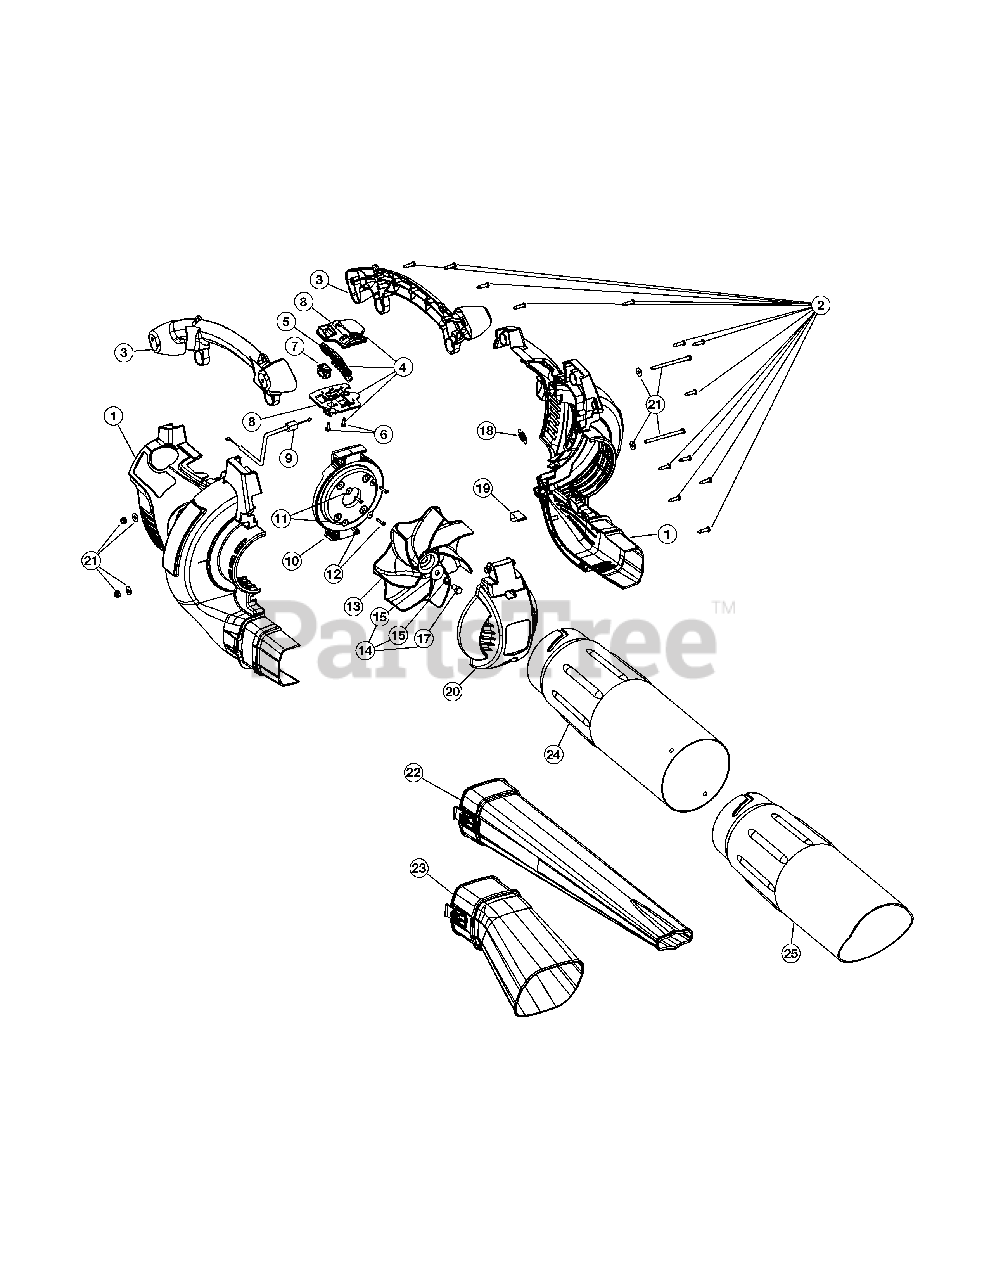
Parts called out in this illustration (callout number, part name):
1	Engine Cover Assm
3	Handle Assm
4	Throttle control Assm
5	Throttle Control Lever
7	Rocker Switch Assm
8	Lower Throttle Control Plate
9	Throttle Cable
10	Engine Mount Plate
13	Impeller Blade
14	Impeller Hardware
15	Washer
16	Lock Washer
18	Vacuum Door Spring
19	Vacuum Door Lock
20	Vacuum Door
21	Mounting Plate Hardware
22	Blower Tube
23	Vacuum Bag Adaptor
24	Upper Vacuum Tube
25	Lower Vacuum Tube
